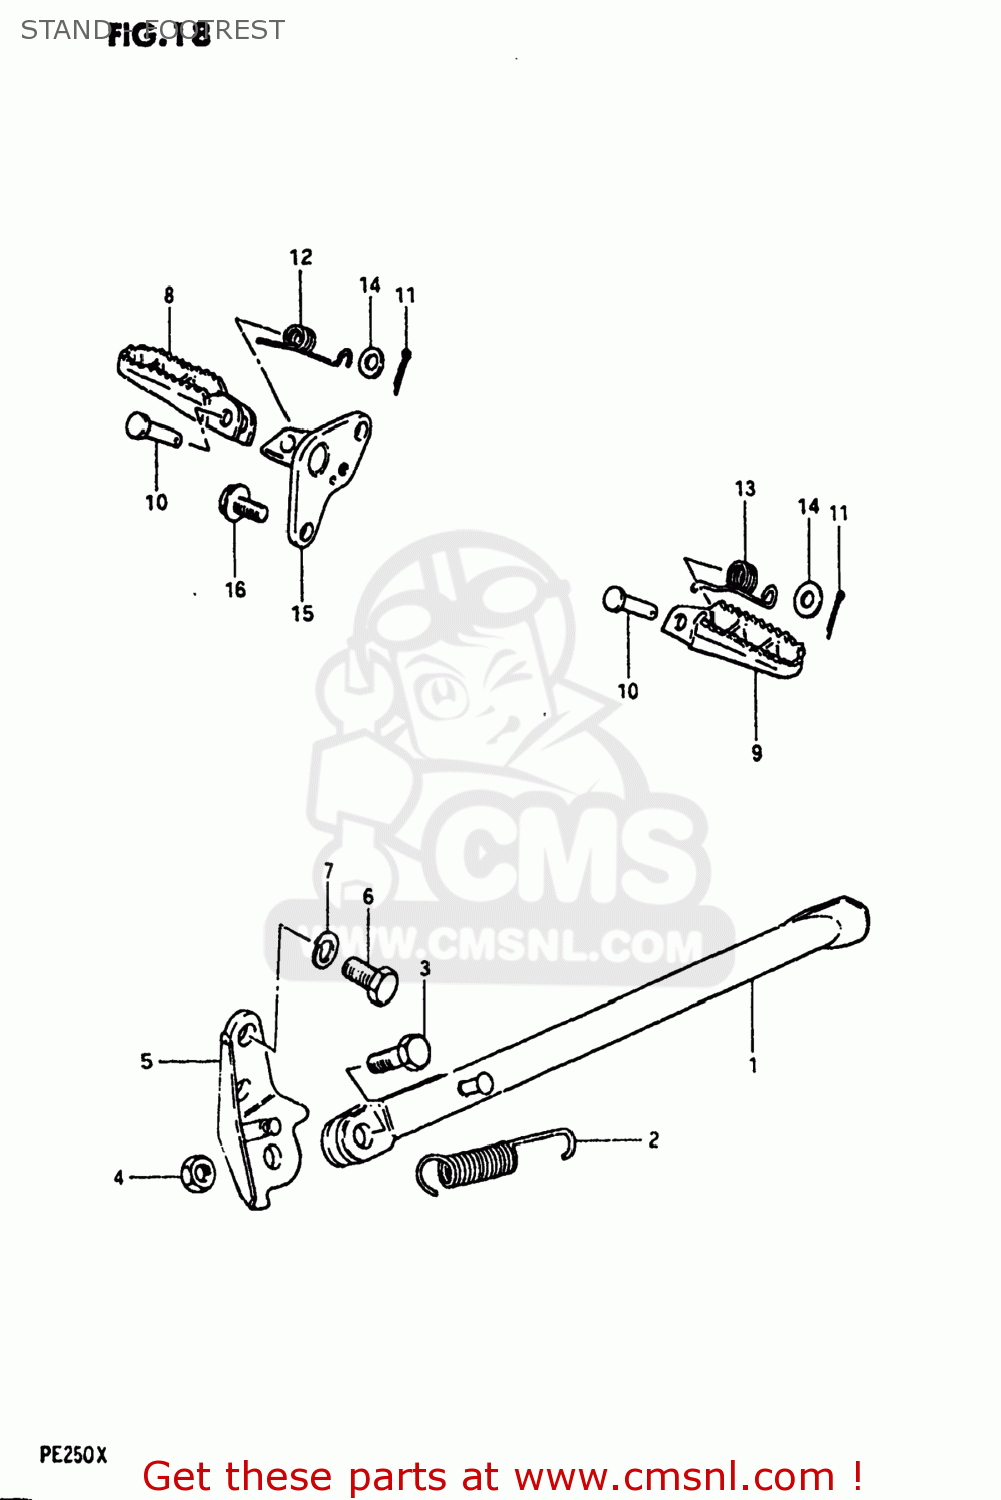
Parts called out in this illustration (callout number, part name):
1	STAND,SIDE
2	SPRING
3	BOLT(10X30)
4	NUT
5	BRACKET,PROP STAND
6	BOLT(10X19)
7	LOCK WASHER
8	RUBBER,FRONT FOOTREST
9	FOOTREST
10	PIN
11	PIN 20X20
12	SPRING
13	SPRING
14	WASHER
15	HOLDER,FRONT FOOTREST,RIGHT
16	BOLT(10X20)
